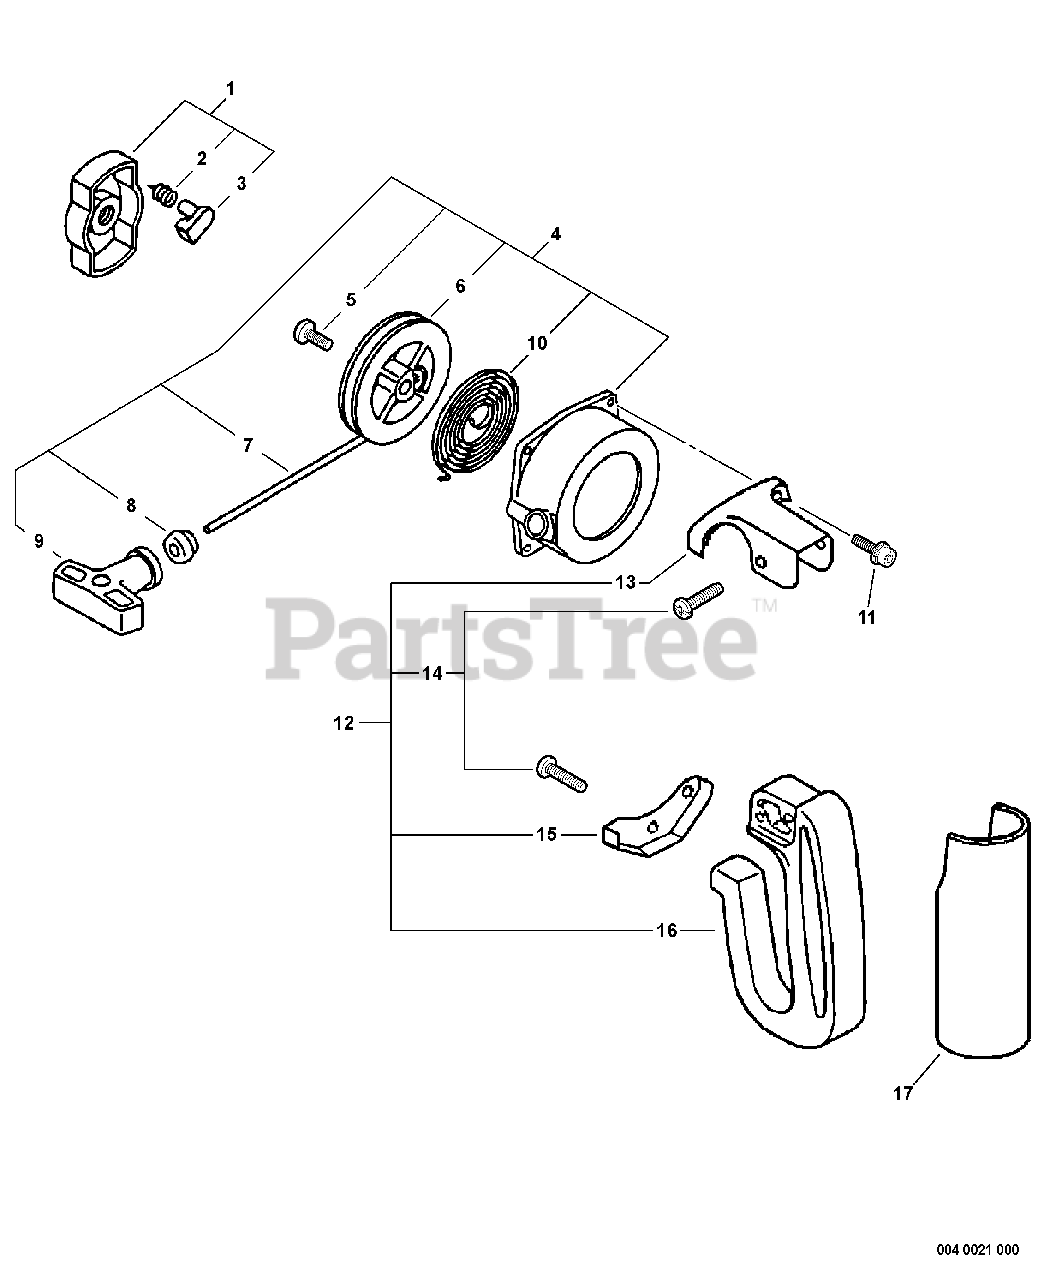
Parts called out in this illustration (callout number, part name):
1	STARTER PAWL ASSY
2	SPRING, RETURN
3	PAWL, STARTER - BLACK
4	STARTER ASSY
6	REEL, ROPE
7	ROPE, STARTER - 3.5X960
8	GUIDE, ROPE
9	GRIP, STARTER
10	SPRING, REWIND
11	SCREW - 4X18
12	SIDE HANDLE ASSY
13	BRACKET, HANDLE - UPPER
14	SCREW - 5X16 -- TAPPING
15	BRACKET, HANDLE - LOWER
16	HANDLE - REAR
17	GRIP, HANDLE
